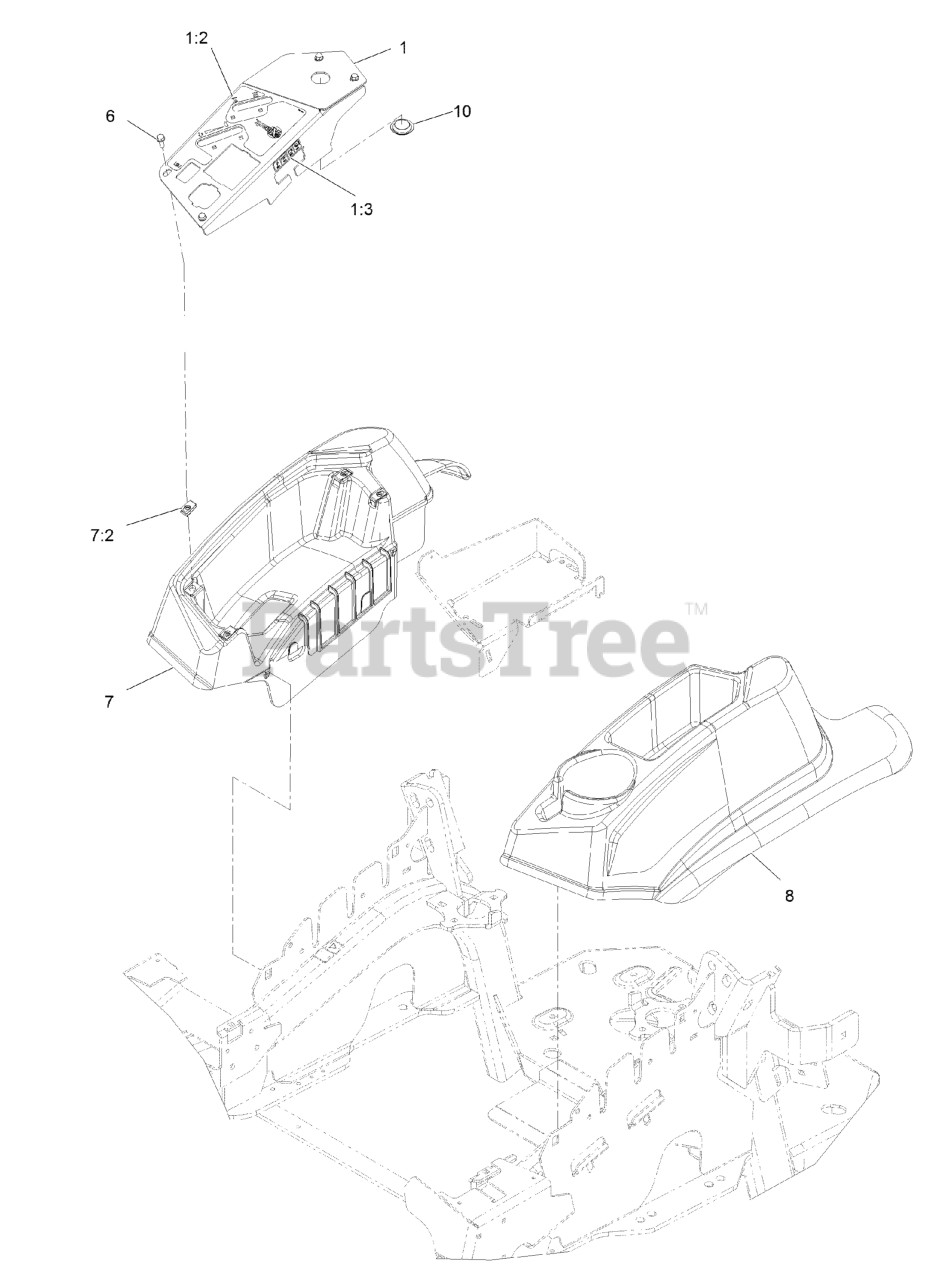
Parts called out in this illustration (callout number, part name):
1	CONSOLE,PANEL W/DECAL
1:2	DECAL-CONTROL PANEL NON-E
1:3	DECAL-FUSES
2	ASM, CHOKE CABLE
3	ASM,THROTTLE CABLE
4	BOLT-CARR
5	NUT-LOCK, NI
6	SCREW-HWH
7	CONSOLE,RH AS ASM
8	CONSOLE, LH AS
9	CLAMP-HOSE
10	PLUG-PLASTIC
